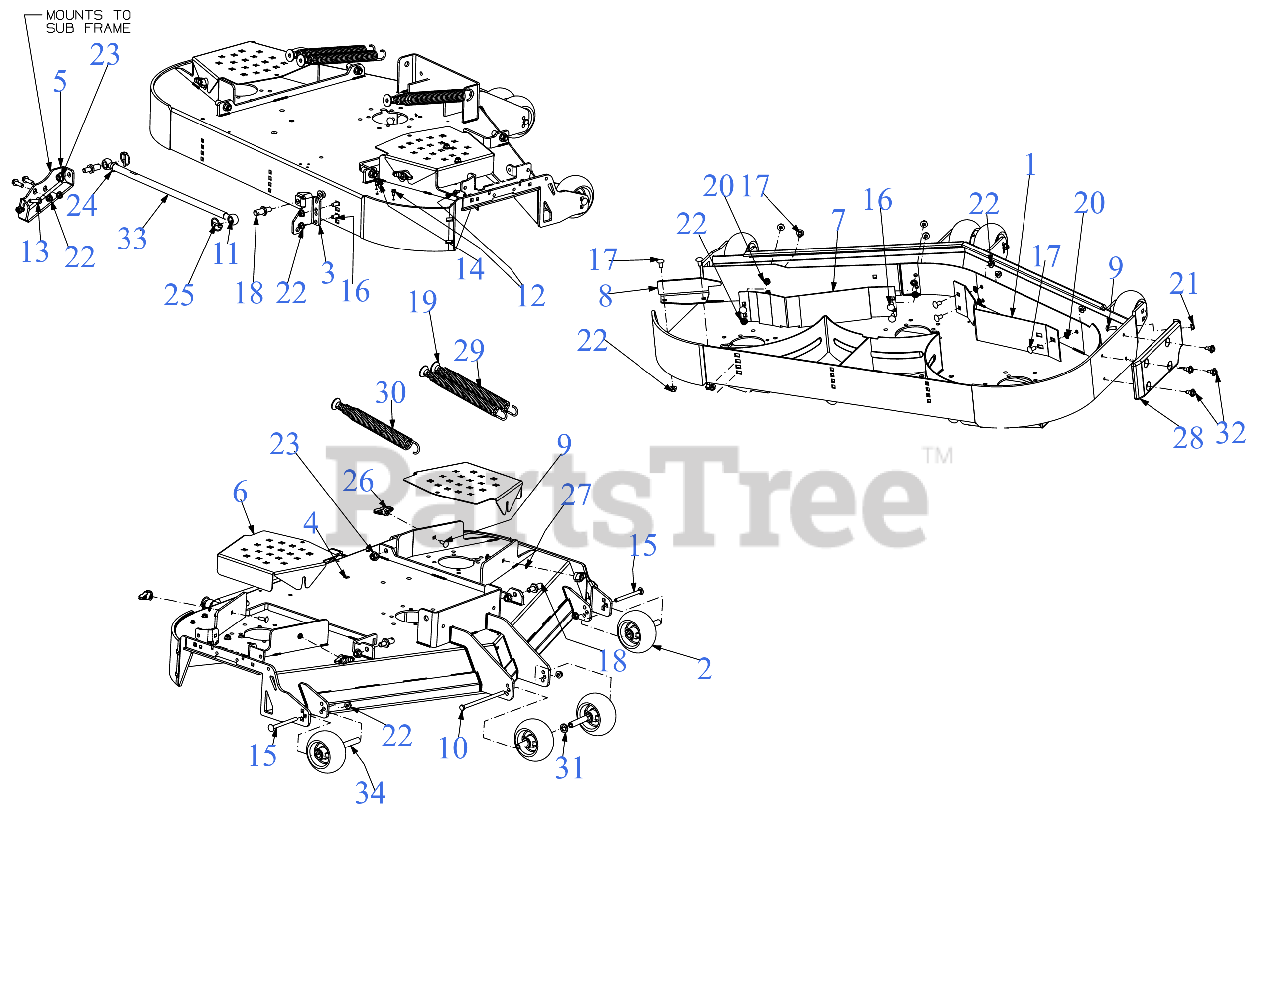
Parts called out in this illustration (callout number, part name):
1	BAFFLE - 54" ADJ
2	5" DIA DECK WHEEL COMPLETE
5	STABILIZER MOUNTING BRACKET
8	DECK CHUTE BAFFLE
9	CARRIAGE BOLT 5/16-18 x 1.00
10	SCREW 3/8-16 x 7.25 GR5
11	BOLT 5/8-16 x 2.63
12	SCREW 1/4-20 X.500
13	SCREW 3/8-16 x 1.25 GR5
14	SCREW 5/16-18 x .500
15	CARRIAGE BOLT 3/8-16 x 4.25 GR5
16	CARRIAGE BOLT 3/8-16 x 1.00 GR5
17	CARRIAGE BOLT 3/8-16 x .75
19	SPRING INSERT SCREW
21	FLANGE LOCK NUT 5/16-18
24	HEX JAM NUT
25	LYNCH PIN .1875
26	WING KNOB 5/16-18
28	DECK SKID PLATE (LH)
29	EXTENTION SPRING 1.20 x 11.35
30	EXTENSION SPRING 1.44 OD x 11.36
31	FLAT WASHER .632X1.00X.16
32	SHOULDER SCREW .43X.29X5/16-18 TT
34	WHEEL SPACER .38ID x 3.04LG
